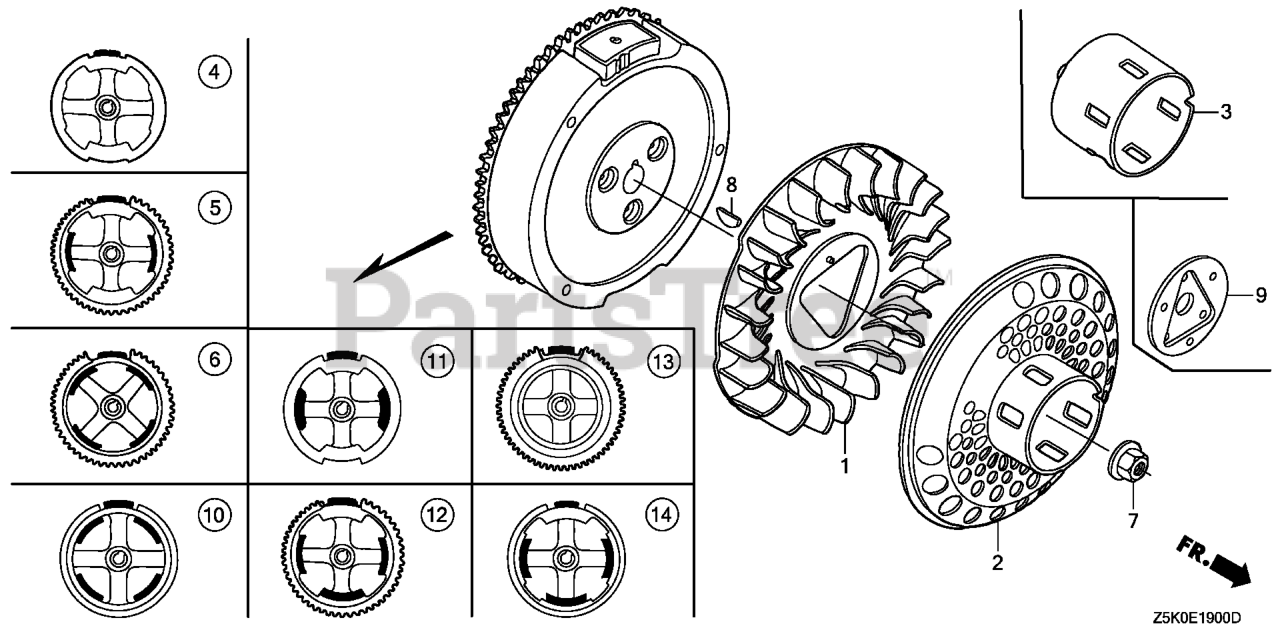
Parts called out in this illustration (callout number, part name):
1	FAN, COOLING
2	PULLEY, STARTER (SCREEN GRID)
7	NUT, SPECIAL (16MM) (1)
7	NUT, SPECIAL (16MM)
8	KEY, SPECIAL WOODRUFF (25X18)
